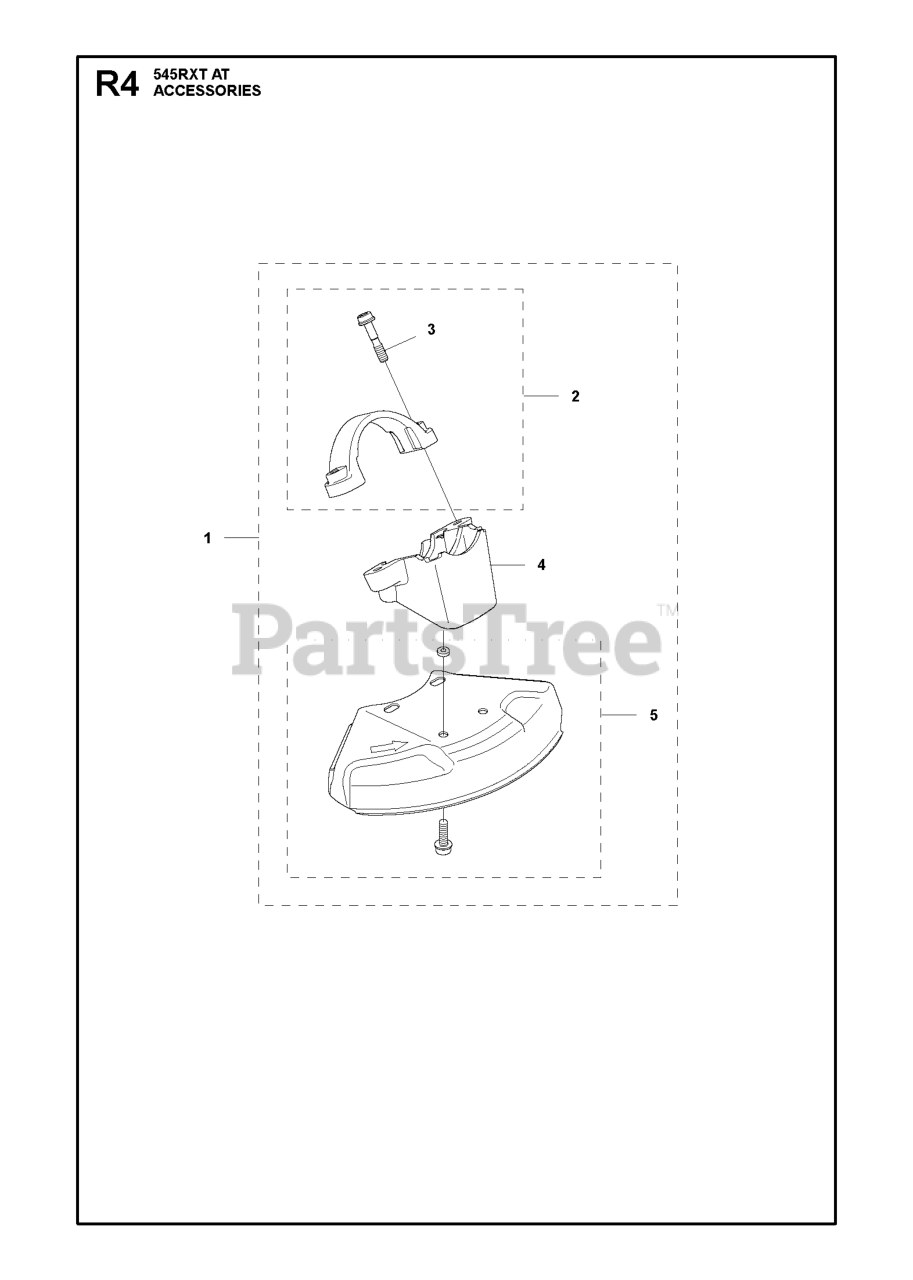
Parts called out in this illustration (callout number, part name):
1	TRIMMER GUARD ASSY
2	CLAMP
3	SCREW IHSCFMO
5	BLADE GUARD
